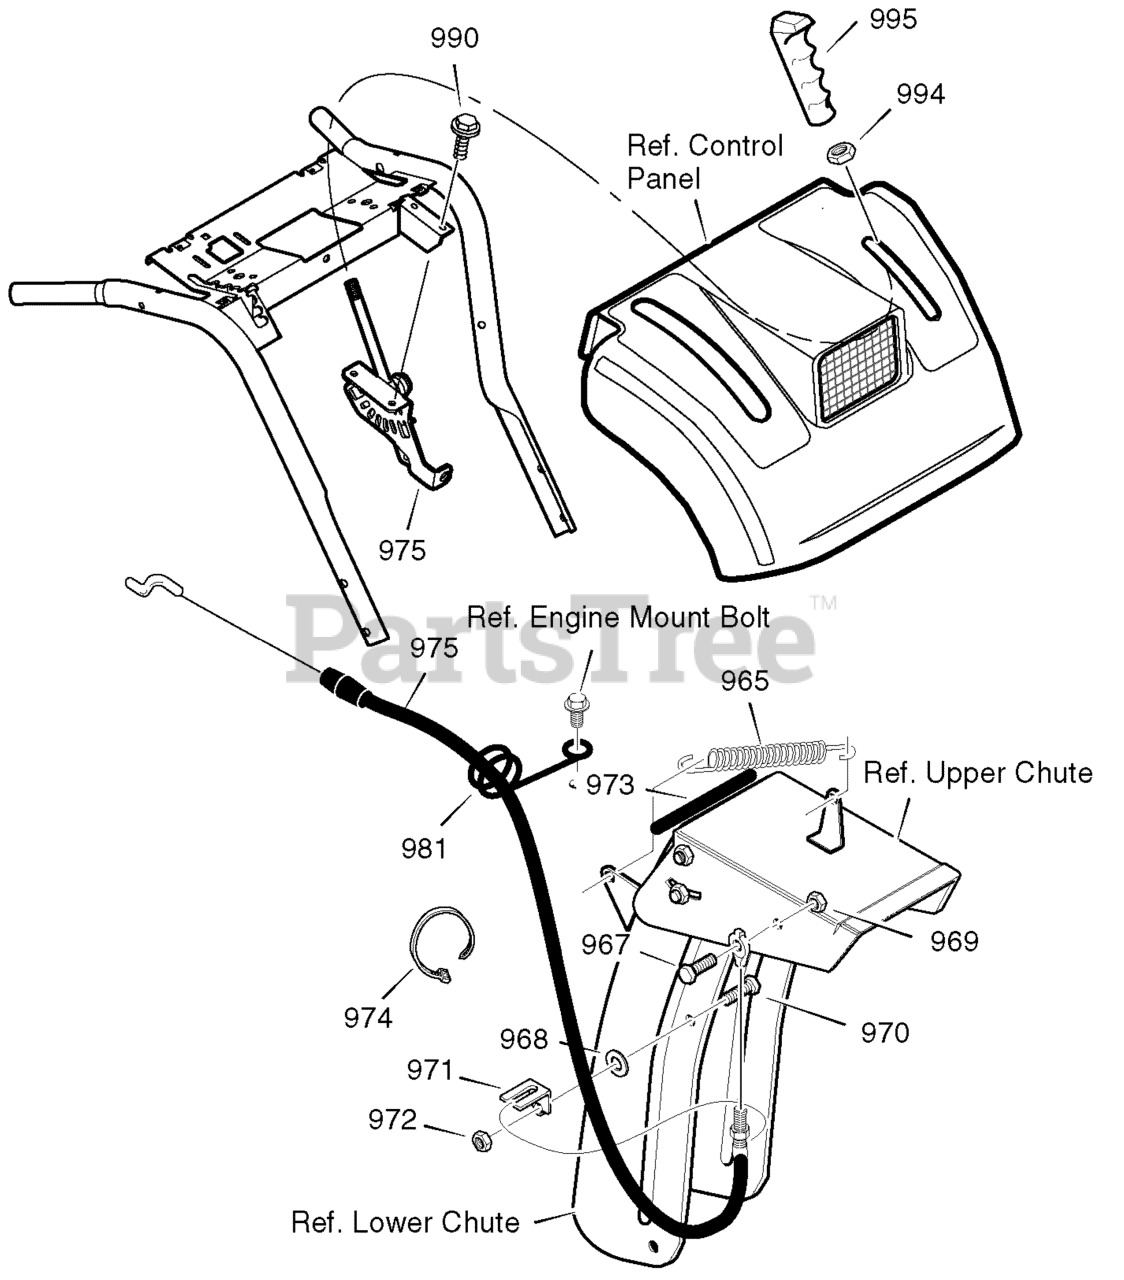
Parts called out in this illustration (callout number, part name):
965	SPRING, RETURN
967	BOLT, 5/16-18
968	WASHER, FLAT
969	NUT, 5/16-18
970	SCREW, 5/16-18 X .75
971	BRACKET, CABLE
972	NUT, 5/16-18
974	TIE, CABLE
975	CABLE, CONTROL
981	WIRE FORM
990	SCREW, 3/8-16 x 1.75
994	NUT, 3/8-16 HEX JAM
995	HANDLE
